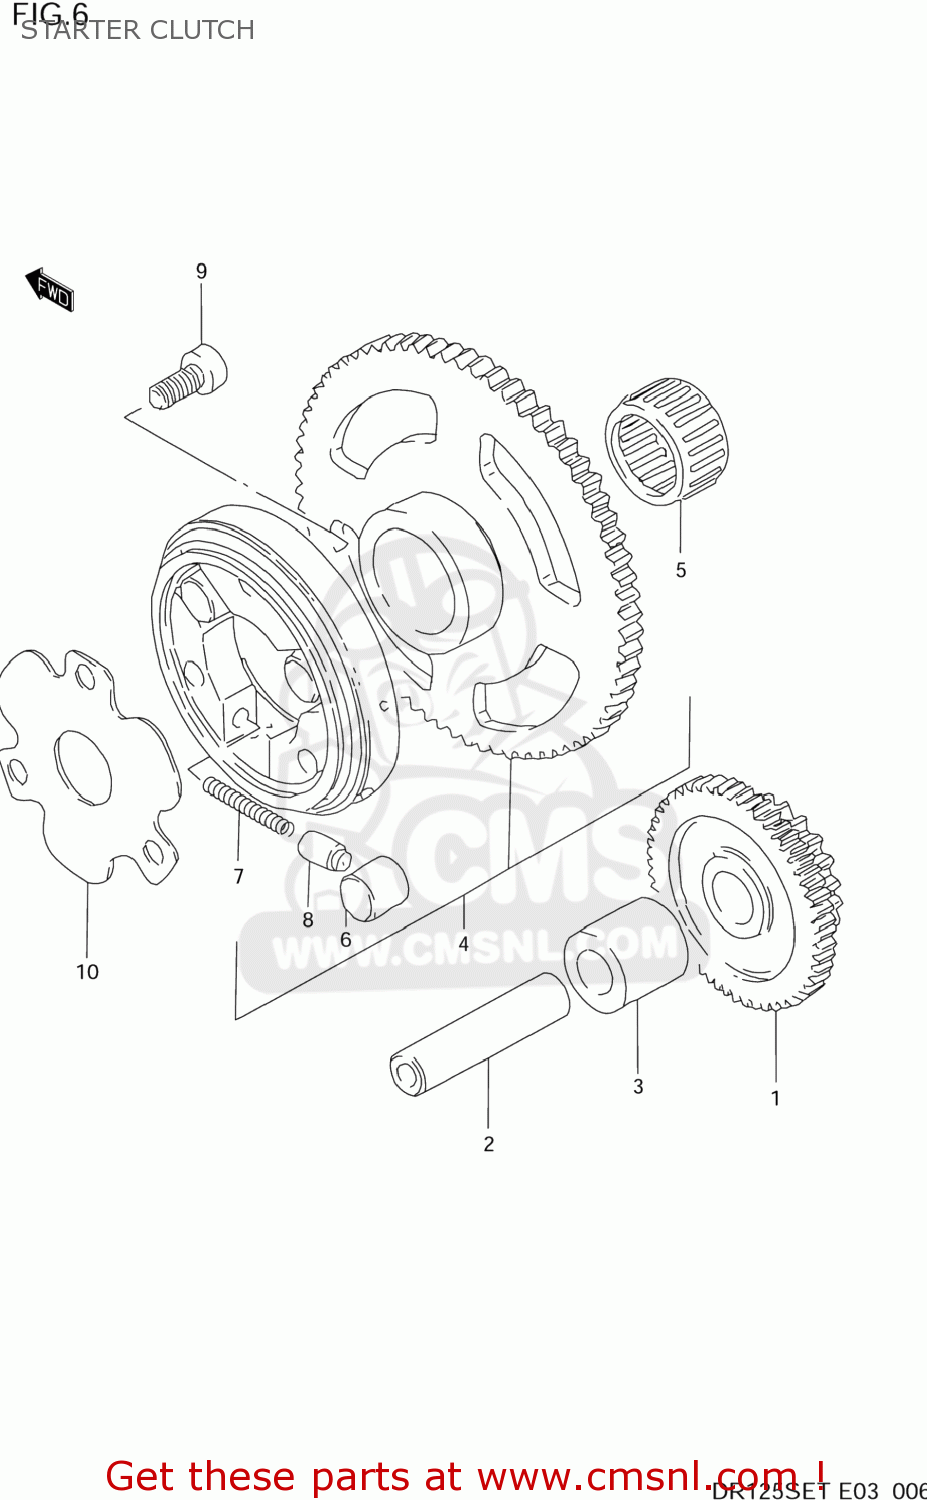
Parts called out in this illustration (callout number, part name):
1	GEAR,STARTER IDLER
2	PIN(7.4X13X56)
3	SPACER(13X19X19)
4	CLUTCH SET,STARTER
5	BEARING(22X28X16)
6	ROLLER(10X11)
7	SPRING
8	PIECE,STARTER CLUTCH PUSH
9	BOLT,OIL FILLE
10	SHIM,STARTER CLUTCH HUB
